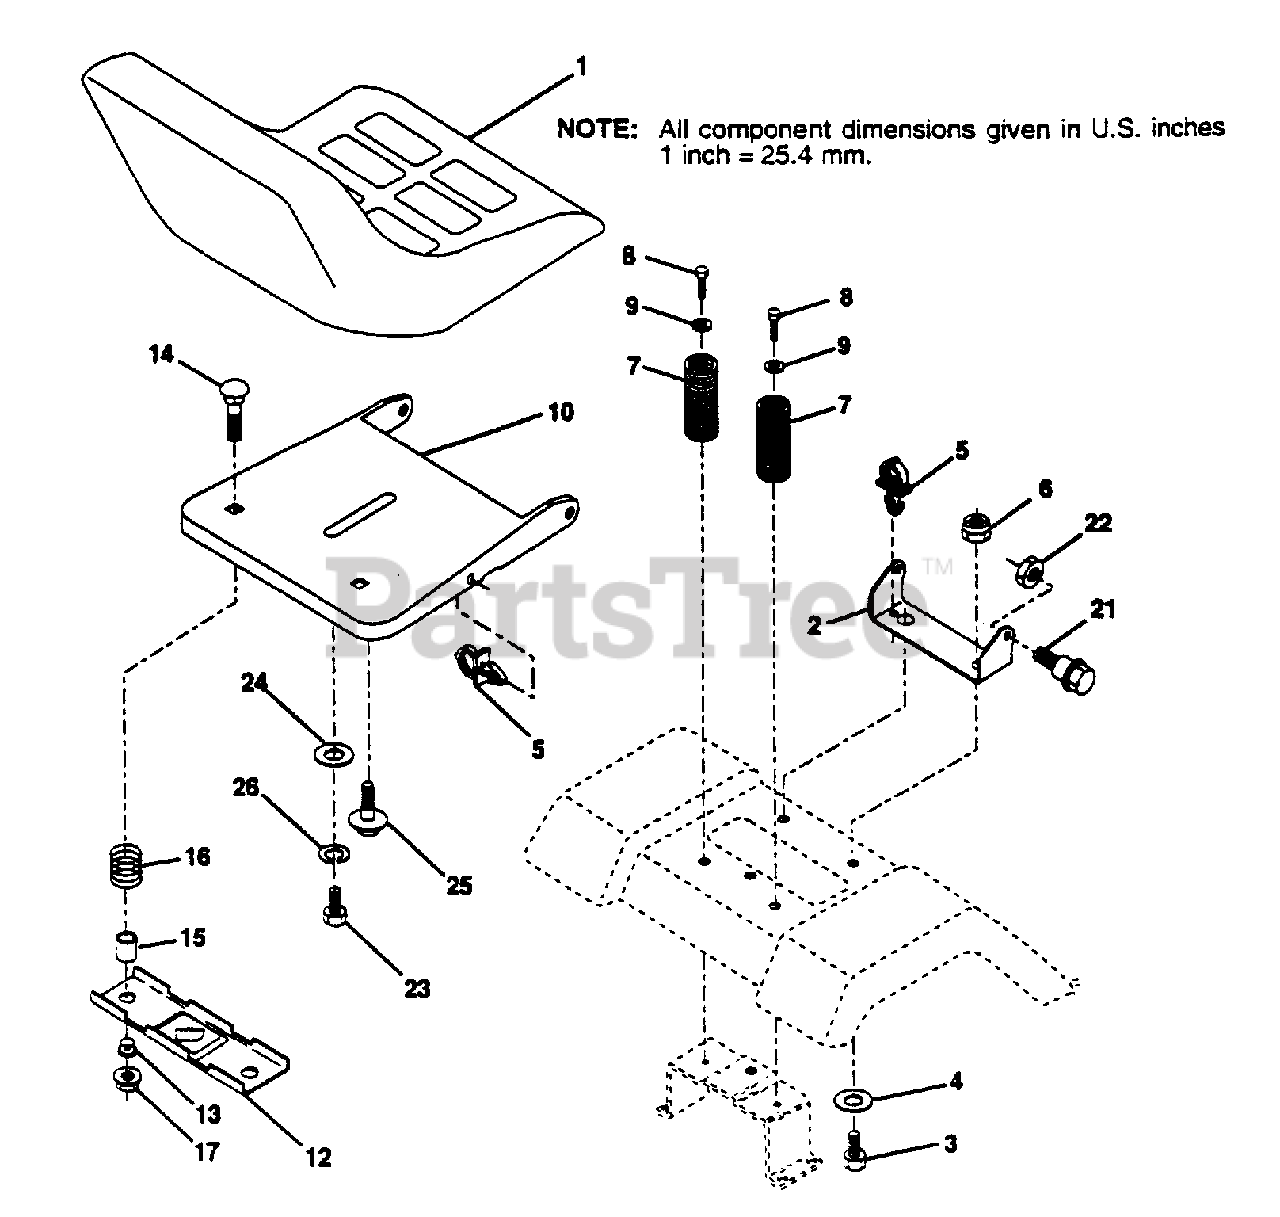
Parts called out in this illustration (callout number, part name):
2	BRACKET PVT SEAT
3	BOLT
4	WASHER PM
5	CLIP.PUSH-IN.HING
6	NUT
7	SPRING COMPRESSIO
8	SCREW GTV
9	WASHER
12	BRKT SWITCH
13	BUSHING
15	SPLIT SPACER
16	SPRING
21	BOLT.SHLD.5/16-18
22	NUT
23	BOLT
24	WASHER
25	"BOLT,SHOULDER"
26	LOCKWASHER
